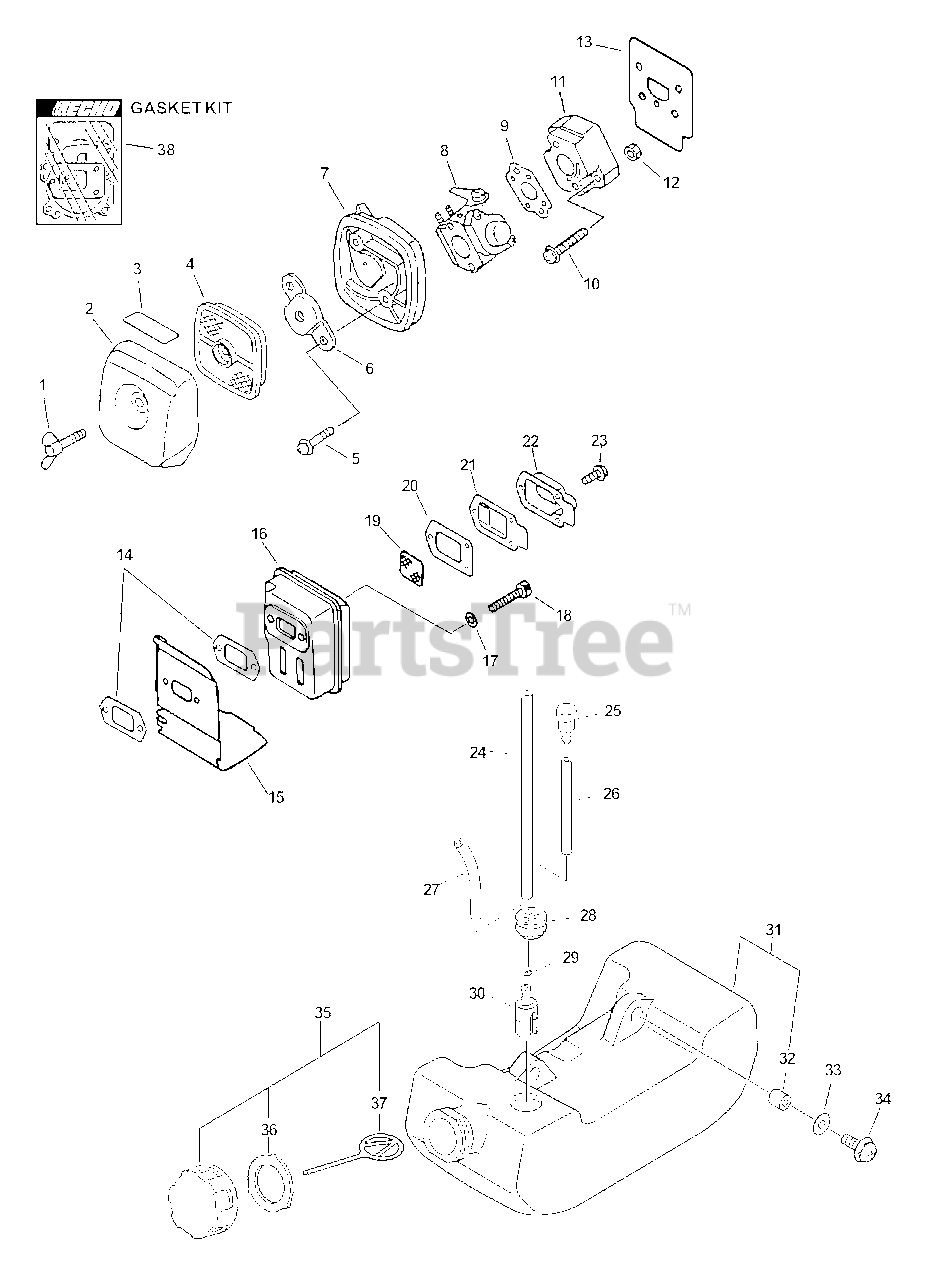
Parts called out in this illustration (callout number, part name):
1	THUMBSCREW
2	COVER, AIR FILTER - GRAY
3	LABEL - CHOKE
4	FILTER, AIR - SINGLE LAYER
5	SCREW - 5X65
6	PLATE, PREVENT
7	AIR FILTER CASE KIT - GRAY
8	CARBURETOR C1U-K52
9	GASKET, INTAKE
10	SCREW - 5X20
11	INSULATOR, INTAKE
13	SHIELD, INTAKE
14	GASKET, EXHAUST
15	SHIELD, EXHAUST
17	WASHER - 5
18	SCREW - 5X55
19	SCREEN, SPARK ARRESTOR
20	GASKET, EXHAUST
21	GUIDE, EXHAUST - OUTER
22	GASKET, EXHAUST - INNER
23	SCREW - 4X10
24	PIPE - 3X5X180 -- BLACK
25	VENT, FUEL TANK
26	PIPE - 3X5X70 -- BLACK
27	PIPE - 3X6X90 -- CLEAR
28	GROMMET
29	CLIP - 6
30	FILTER, FUEL
31	FUEL TANK ASSY
33	WASHER - 5
34	SCREW - 5X16
35	CAP ASSY - ORANGE
36	GASKET, CAP
37	CONNECTOR, CAP
38	GASKET KIT
